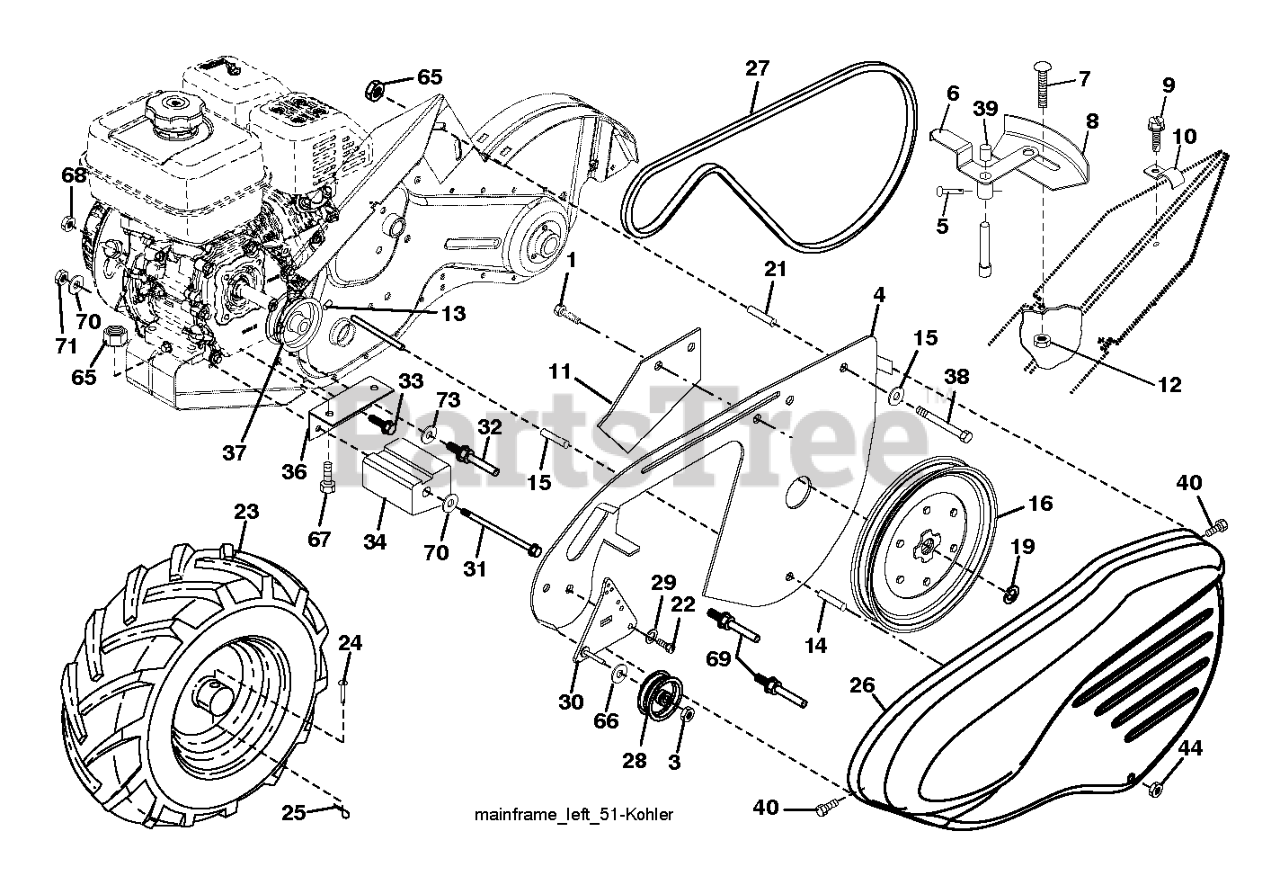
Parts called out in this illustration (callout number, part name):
1	SCREW.HEX.WASH.HD.TAPPING
3	LOCKNUT
4	SHIELD.INNER.BELT.GUARD.RT.BLA
5	PIN.SPIROL.FLARED
6	LEVER ASM CRT
8	PANEL.INDICATOR.SHIFT.BLACK
9	TAPPING SCREW
10	CONDUIT.CLIP.PLATED
11	GUARD.RT TILLER.CRT/DRT.CE
12	NUT
14	SPACER-SPLIT.327 X .42
16	SHEAVE, TRANSMISSION
19	RETAINING RING LT
21	SPACER SPLIT .420 X .327
23	WHEEL 16X4X8 DR TILLER LH.417
24	RIVET
25	RETAINER M
26	GUARD.BELT.TILLER.ORANGE
27	V-BELT
28	PULLEY-IDLER TI
30	BRACKET.IDLER.ASM.LONG
31	BOLT.FIN.HEX.3/8-16UNC X 11.5
32	SHIFT ARM CRT
33	BOLT
34	COUNTERWEIGHT.LH
36	BRACKET.REINFORCEMENT.LH.PNT
37	PULLEY ENGINE 4L 2.50
38	BOLT
39	CAP.PLUNGER.BLACK
40	SCREW.HEX.WSH.SLT.#10-24X.50
44	NUT.71038.31-18.HEX.NYLOCK
65	LOCKNUT-FLANGE 5/16-18
66	WASHER
67	BOLT, HEX 5/16-18X1-3/4
69	KEEPER.BELT.ENGINE
70	WASHER
73	WASHER
